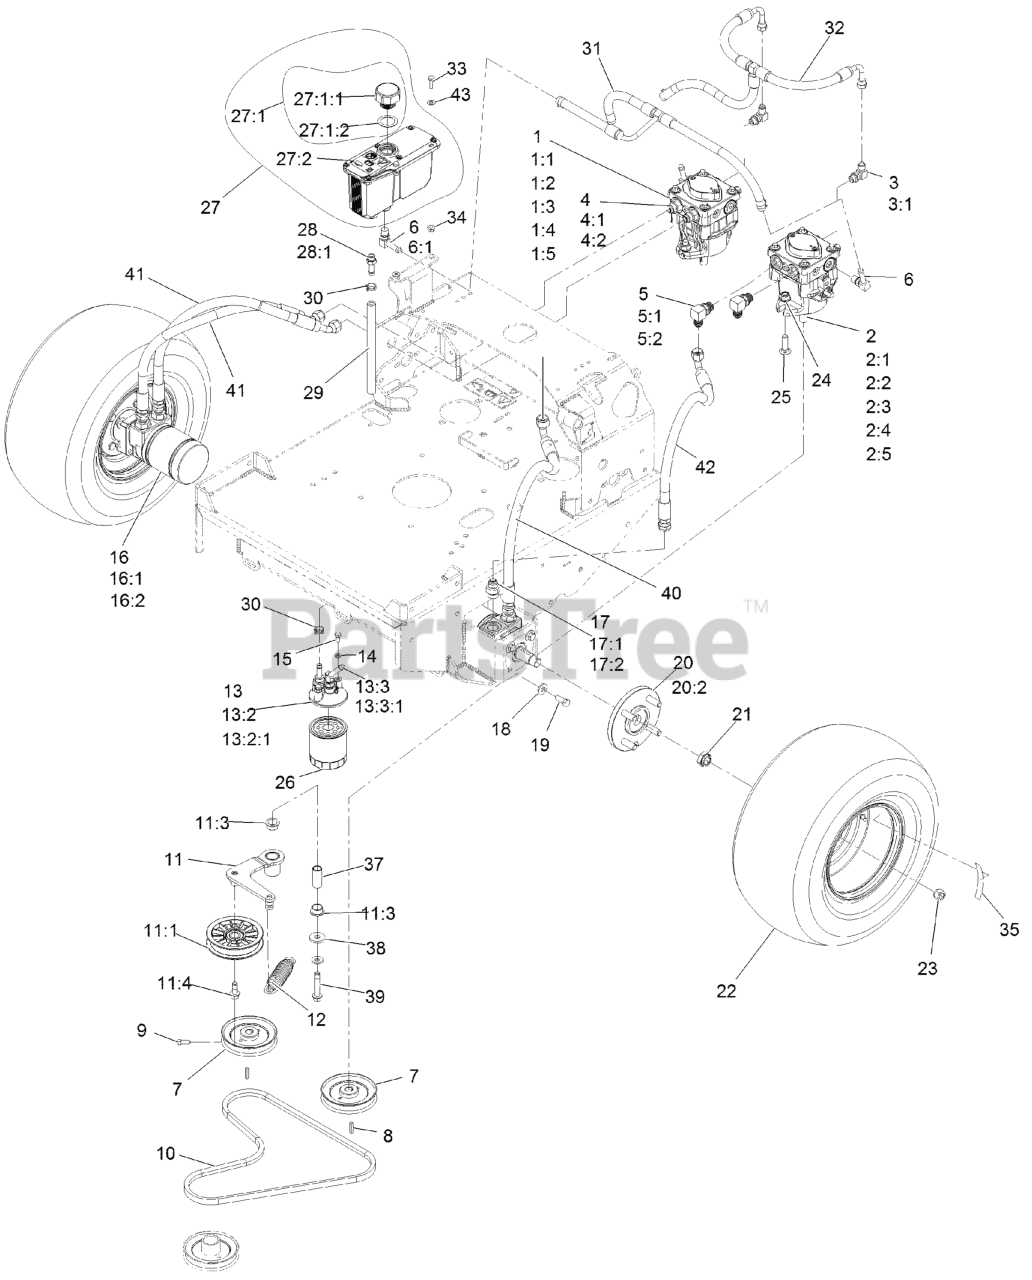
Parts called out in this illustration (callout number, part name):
1	PUMP-HYD PE RH TTH
1:1	INPUT SHAFT KIT
1:2	BEARING-THRUST
1:3	CYLINDER BLOCK KIT
1:4	SEAL OVERHAUL KIT
1:5	KIT, 10CC PUMP KIT
2	PUMP-HYD PE LH TTH
2:1	INPUT SHAFT KIT
2:2	BEARING-THRUST
2:3	CYLINDER BLOCK KIT
2:4	SEAL OVERHAUL KIT
2:5	KIT, 10CC PUMP KIT
3	FITTING-ELBOW, 90 DEG
3:1	O-RING
4	FITTING-STRAIGHT
5	FITTING-90 DEG
6	FITTING-ELBOW, 90
6:1	O-RING
7	SHEAVE ASM
9	SCREW-SET, SQH
10	BELT
11	ASM, PUMP IDLER
11:1	PULLEY-IDLER, FLAT
11:3	BUSHING-FLANGE
11:4	SCREW-HFH
12	SPRING-EXTENSION
13	ASM, FILTER HEAD
13:2	ADAPTER-STRAIGHT
13:2:1	O-RING
13:3	FITTING-BARBED, 45 DEG
13:3:1	O-RING
14	WASHER-LOCK
15	SCREW-HH
16	HYD MOTOR ASM
16:1	SEAL KIT
16:2	BEARING AND SEAL KIT
17	FITTING-STRAIGHT
17:1	O-RING
18	WASHER-BELLEVILLE
19	SCREW-HH
20	WHEEL HUB ASM
20:2	STUD-WHEEL
21	NUT-LOCK
22	ASM, DRIVE TIRE
23	NUT-LUG
24	NUT-HF, NI
25	BOLT-CARR
26	FILTER-25 MICRON, BI-DIRE
27:1	Reservoir-HYD
27:1:1	Cap-Reservoir, HYD
27:1:2	GASKET-CAP
27:2	DECAL-WARNING
28	ADAPTER-STRAIGHT
28:1	O-RING
29	HOSE-CHARGE
30	CLAMP-HOSE
31	HOSE, CASE
32	HOSE, CHARGE
33	SCREW-HH
34	NUT-HHF
35	DECAL-TORQUE WHEEL LUG-HU
37	PIVOT, IDLER
39	SCREW-HHF W/ PATCH
40	ASM, HP HOSE
41	HOSE,HYDRAULIC W/COVER
42	HYD HOSE ASM
43	WASHER-FLAT
